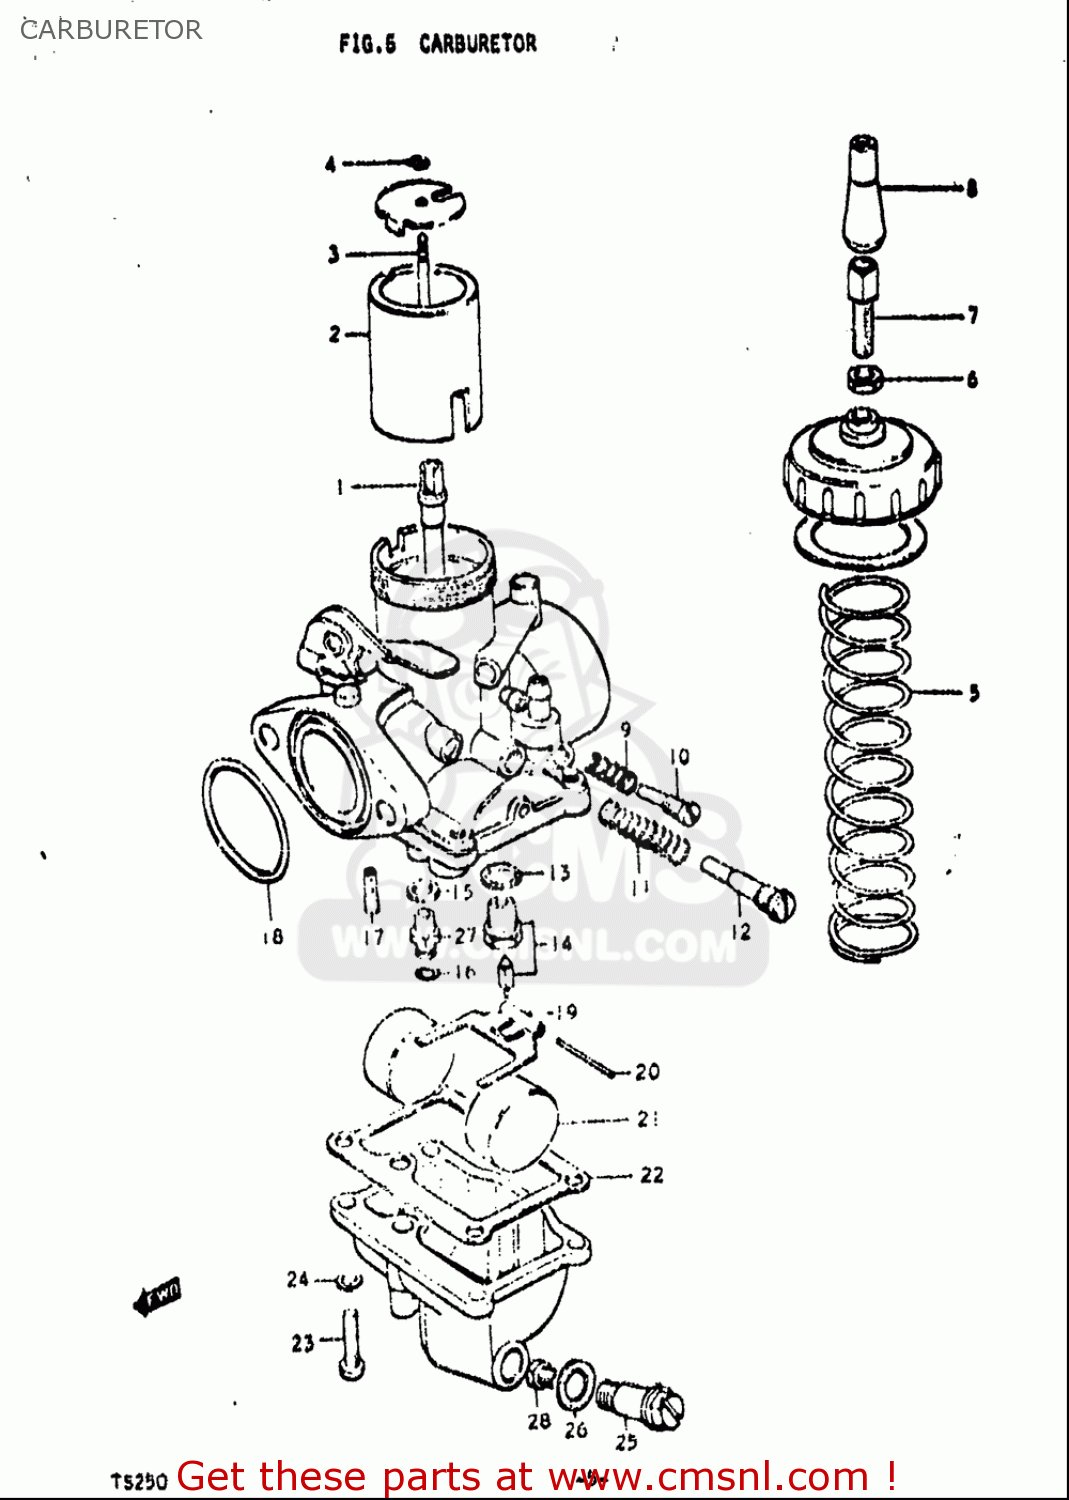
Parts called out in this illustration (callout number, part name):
3	NEEDLE,JET(5CN3)
4	CLIP
6	NUT
7	ADJUSTER,CABLE
8	CAP
9	SPRING
10	SCREW,PILOT AIR
11	SPRING,THROTTLE SCREW
12	SCREW,THROTTLE STOP
13	GASKET,VALVE SEAT (NAS)
14	VALVE ASSY,NEEDLE
15	WASHER
16	O RING
17	JET,PILOT(25)
21	FLOAT
22	GASKET,FLOAT CAHMBER (NAS)
23	SCREW 4X16
24	WASHER,LOCK
26	WASHER
28	JET,MAIN(180)
